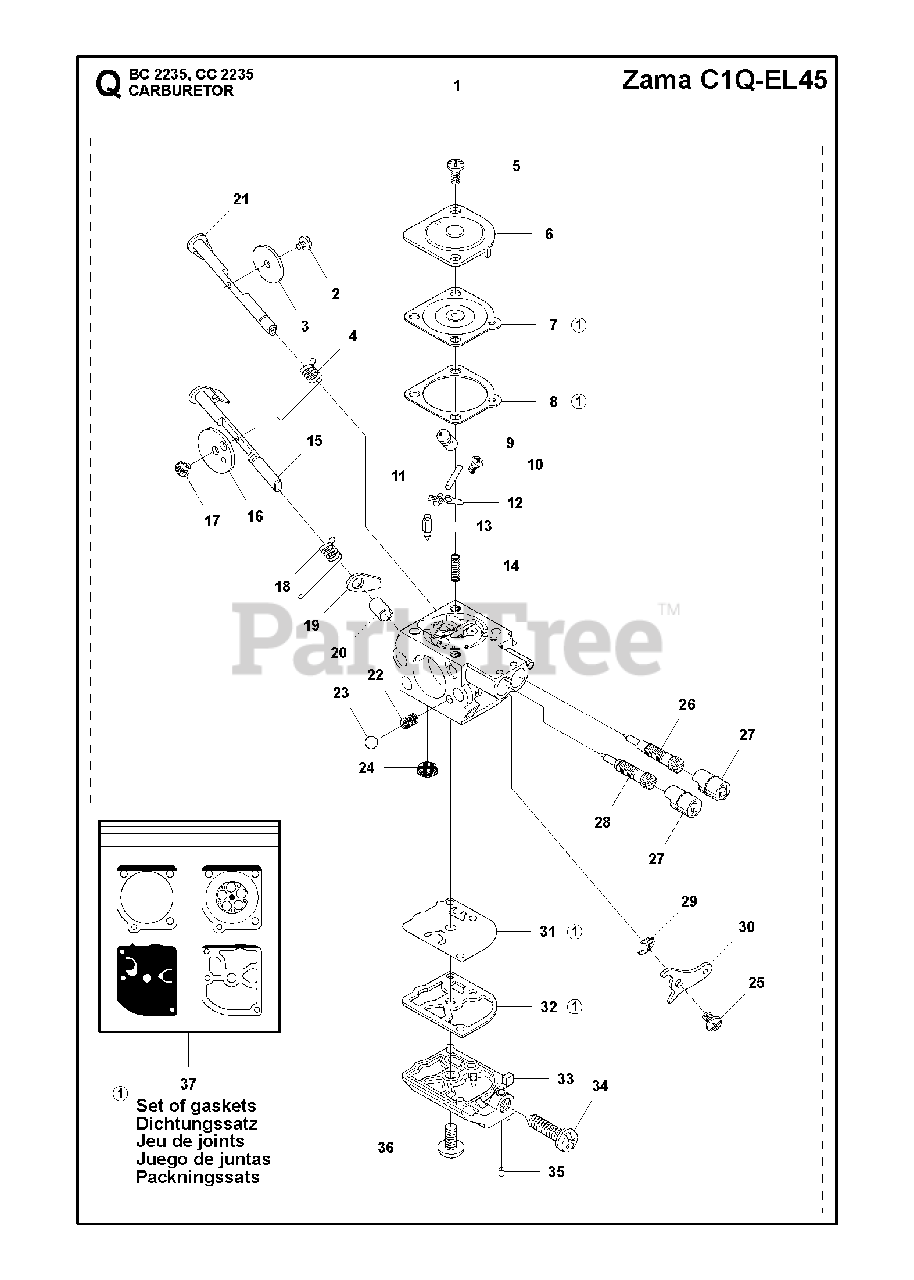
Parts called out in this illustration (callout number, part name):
1	CARBURETOR
2	SCREW
3	THROTTLE
4	RETURN SPRING
5	SCREW
6	COVER
7	DIAPHRAGM
8	GASKET
9	JET
10	SCREW
11	PIN FULCRUM
12	LEVER
13	INLET NEEDLE
14	SPRING
15	SHAFT ASSY
16	CHOKE CAP
17	SCREW
18	SPRING
19	LEVER
20	SLEEVE
21	SHAFT ASSY
22	SPRING
23	BALL
24	FUEL INLET SCREEN
25	SCREW
26	IDLE SCREW
27	LIMITER CAP KIT
28	SCREW
29	CLIP
30	THROTTLE LEVER
31	PUMP DIAPHRAGM
32	GASKET
33	COVER
34	SCREW
35	PLUG
36	SCREW
37	GASKET KIT (ZAMA GND39)
